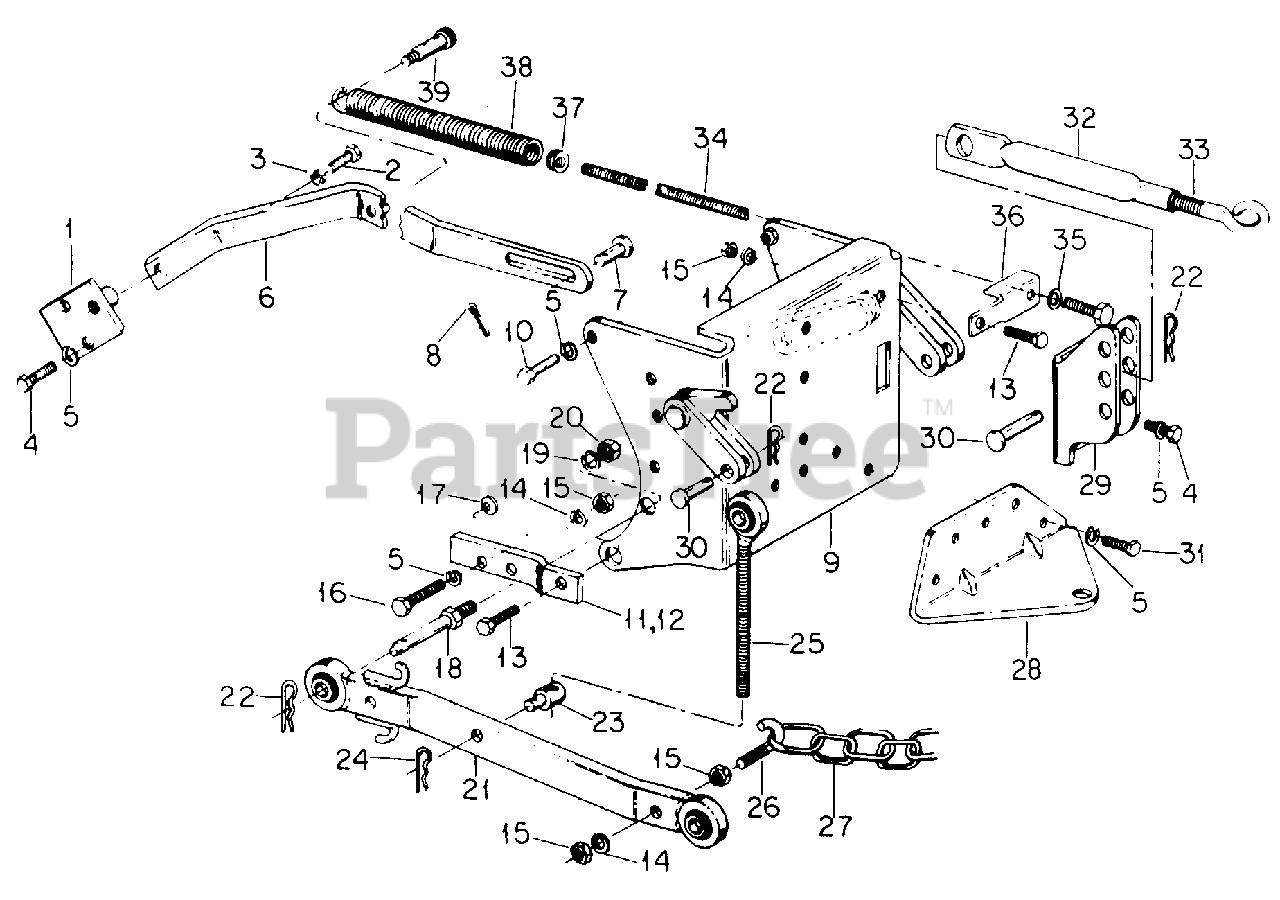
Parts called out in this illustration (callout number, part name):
1	Block Assy, Lift
2	Bolt, 1/2 X 1 Type 5
3	Sleeve, .50 X .62 X .37
4	Bolt, 3/8 X 7/8 Type 5
5	Washer, 3/8 Lock
6	Bar, Lift
7	Pin, Clevis
8	Pin, 1/8 X 1 Cot
9	Plate Assy, Three Point Hitch
10	Bolt, 3/8 X 3/4 Type 5
14	Washer, 7/16 Lock
15	Nut, 7/16 Cad P/T Lock Type 5
16	Bolt, 3/8 X 2-1/2 Type 5
17	Washer, 3/8 ID Belleville
18	Link, Clevis Pin
19	Washer, 5/8 Lock
20	Nut, 5/8 Cad P/T Lock Type 5
21	Bar Assy, Draft
23	Ferrule, Adjustment
25	Link Assy, Adjustable Lift
26	Hook, Hitch Chain
27	Chain, Limiter
30	Pin, 5/8 X 2.000 Pln Clevis
31	Bolt, 3/8 X 1 Type 5
33	Screw, Clevis
35	Washer, .406 X .812 X .065 Hdn
36	Anchor, Spring
37	Insert, Spring
38	Spring, Assist
39	Bolt, Shoulder
